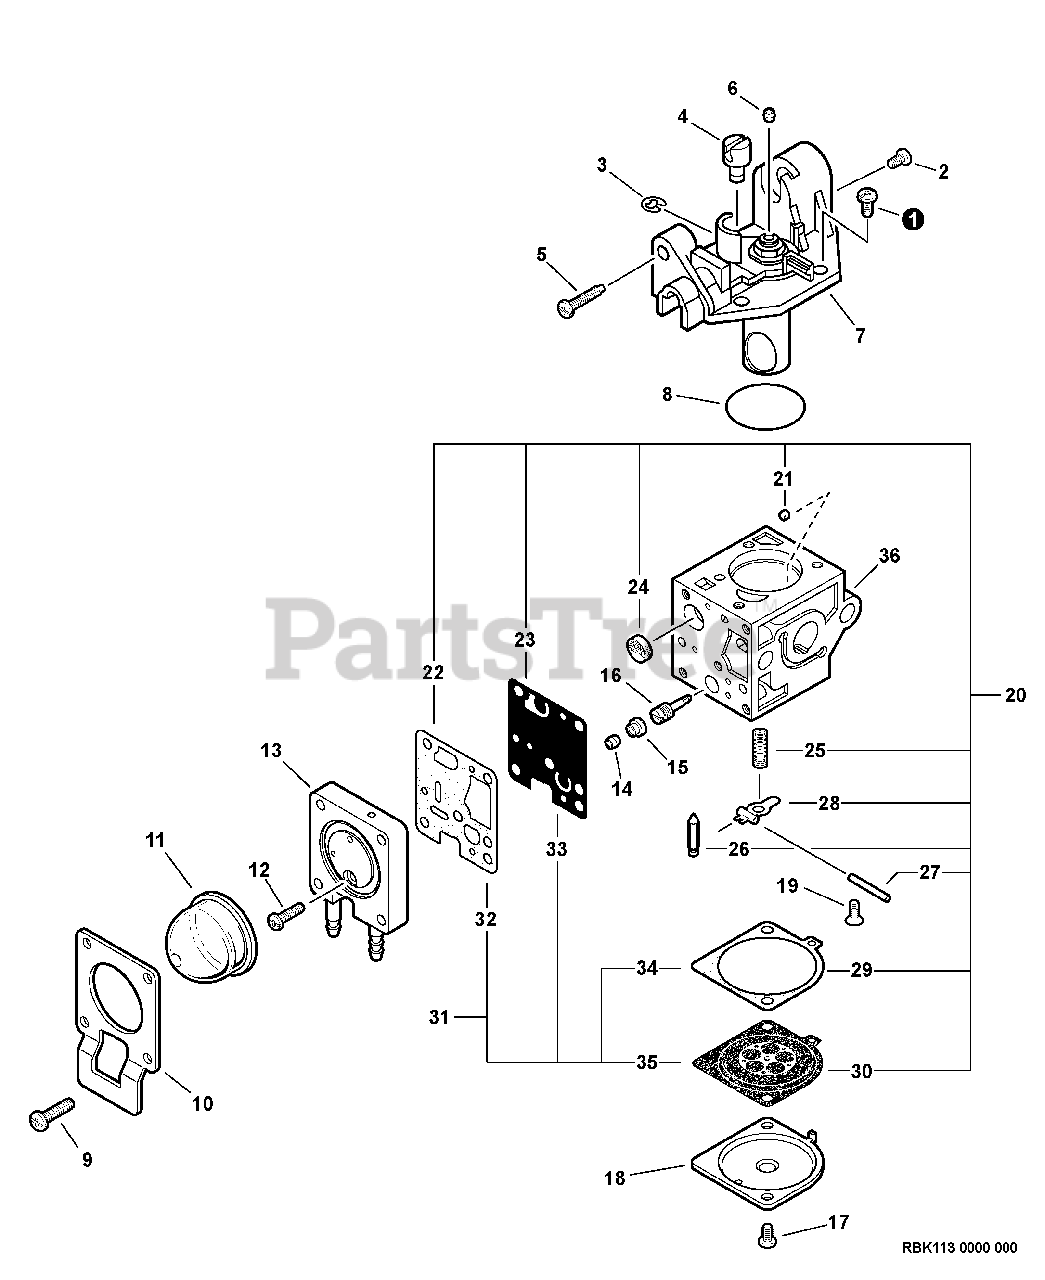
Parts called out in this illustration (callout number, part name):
3	RING, RETAINING
5	SCREW, IDLE ADJUST
7	ROTOR COVER ASSY
9	SCREW, RETAINER
10	RETAINER, PURGE BULB
11	BULB, PURGE
12	SCREW, PURGE BASE
13	BASE, PURGE
15	CAP, LIMITER
16	NEEDLE - HIGH SPEED
18	COVER, METERING
19	SCREW, METERING LEVER PIN
20	REPAIR KIT
21	GUIDE, ROLLER
22	GASKET, PUMP
23	DIAPHRAGM, PUMP
24	STRAINER
25	SPRING, METERING LEVER
26	VALVE, INLET NEEDLE
27	PIN, METERING LEVER
28	LEVER, METERING
29	GASKET, METERING
30	DIAPHRAGM, METERING
31	DIAPHRAGM/GASKET KIT
32	GASKET, PUMP
33	DIAPHRAGM, PUMP
34	GASKET, METERING
35	DIAPHRAGM, METERING
36	BODY, CARBURETOR
